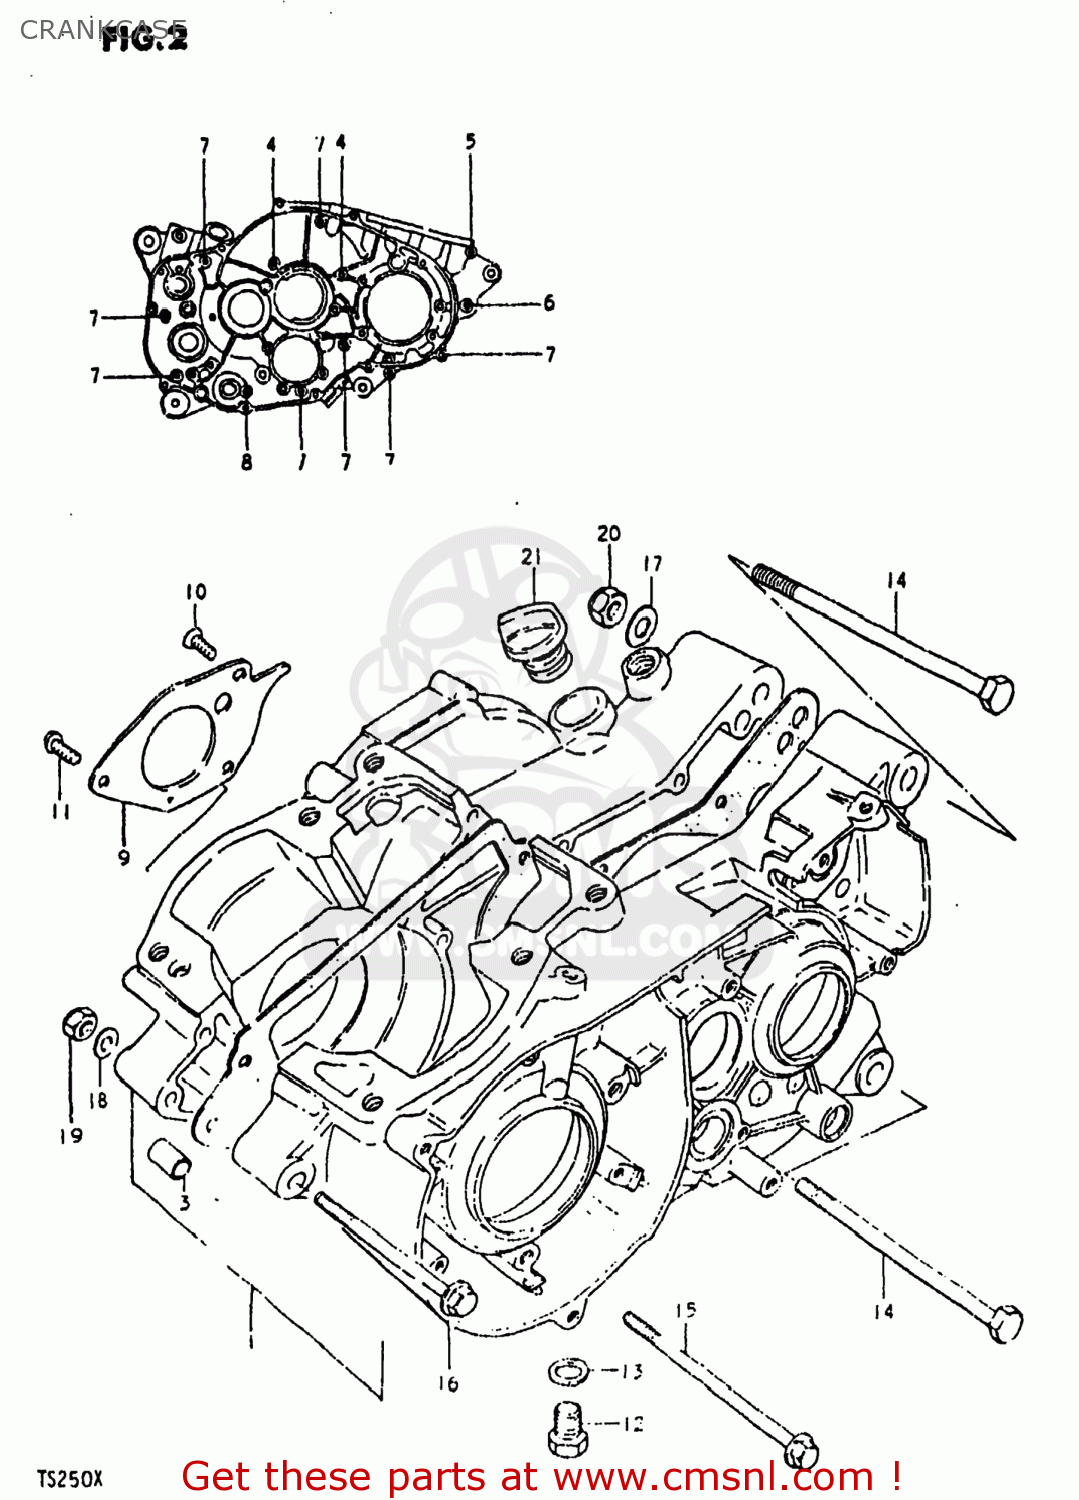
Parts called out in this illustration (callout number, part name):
1	CRANKCASE SET
2	GASKET,CRANKCASE (MCA)
3	PIN
4	SCREW
5	SCREW 6X65
6	SCREW
7	SCREW (6X45)
8	SCREW (6X35)
9	PLATE,OIL RESERVOIR
10	SCREW
11	SCREW
12	PLUG
13	GASKET(14X19.2X2) (NAS)
14	BOLT
15	BOLT
16	BOLT
17	WASHER
18	WASHER
19	NUT
20	NUT
21	PLUG
